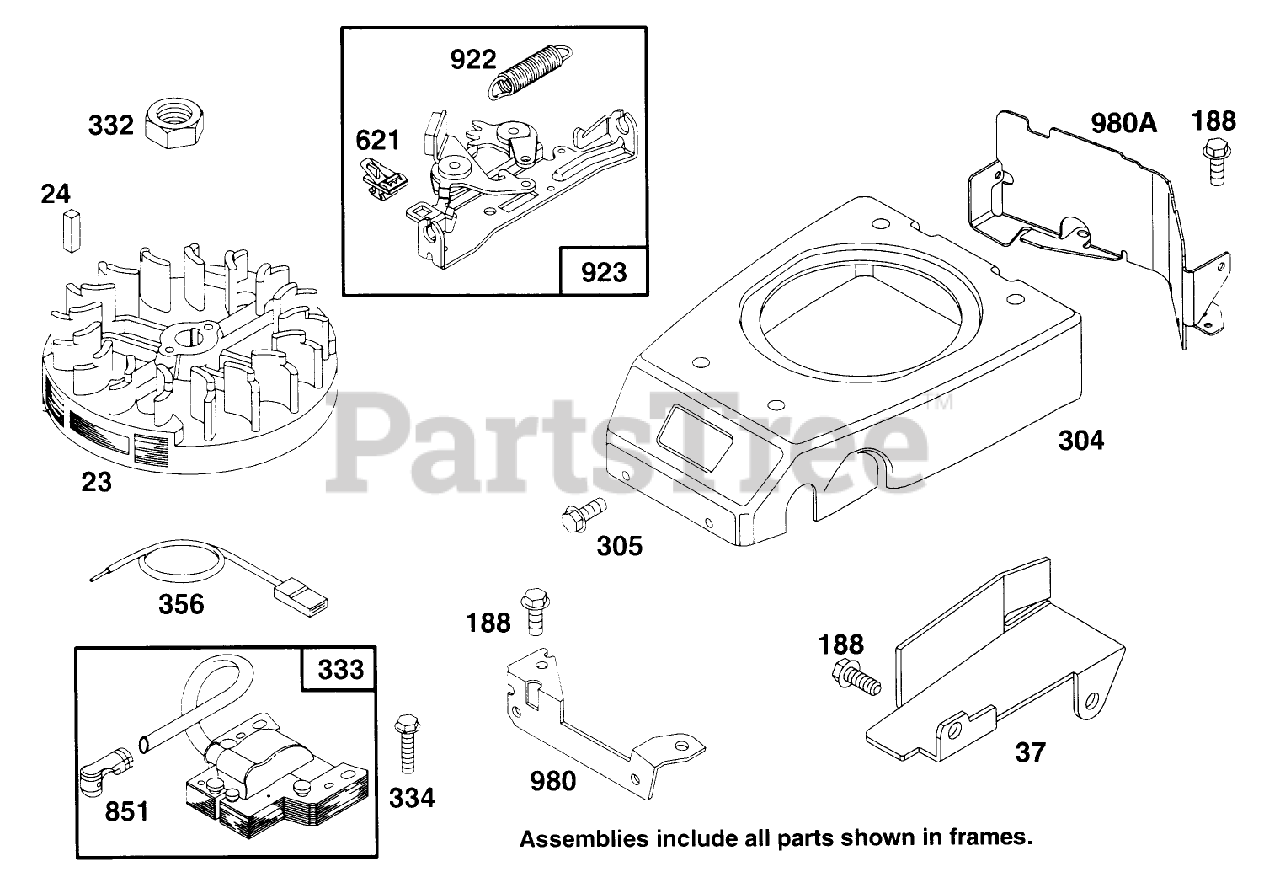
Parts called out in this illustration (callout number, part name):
24	KEY - FLYWHEEL
304	HOUSING - BLOWER
305	SCREW - HEX HEAD
332	NUT - HEXAGON
356	WIRE - GROUND
621	STOP SWITCH
980	Bracket-Blower Housing
980A	BLOWER HSG BRACKET
